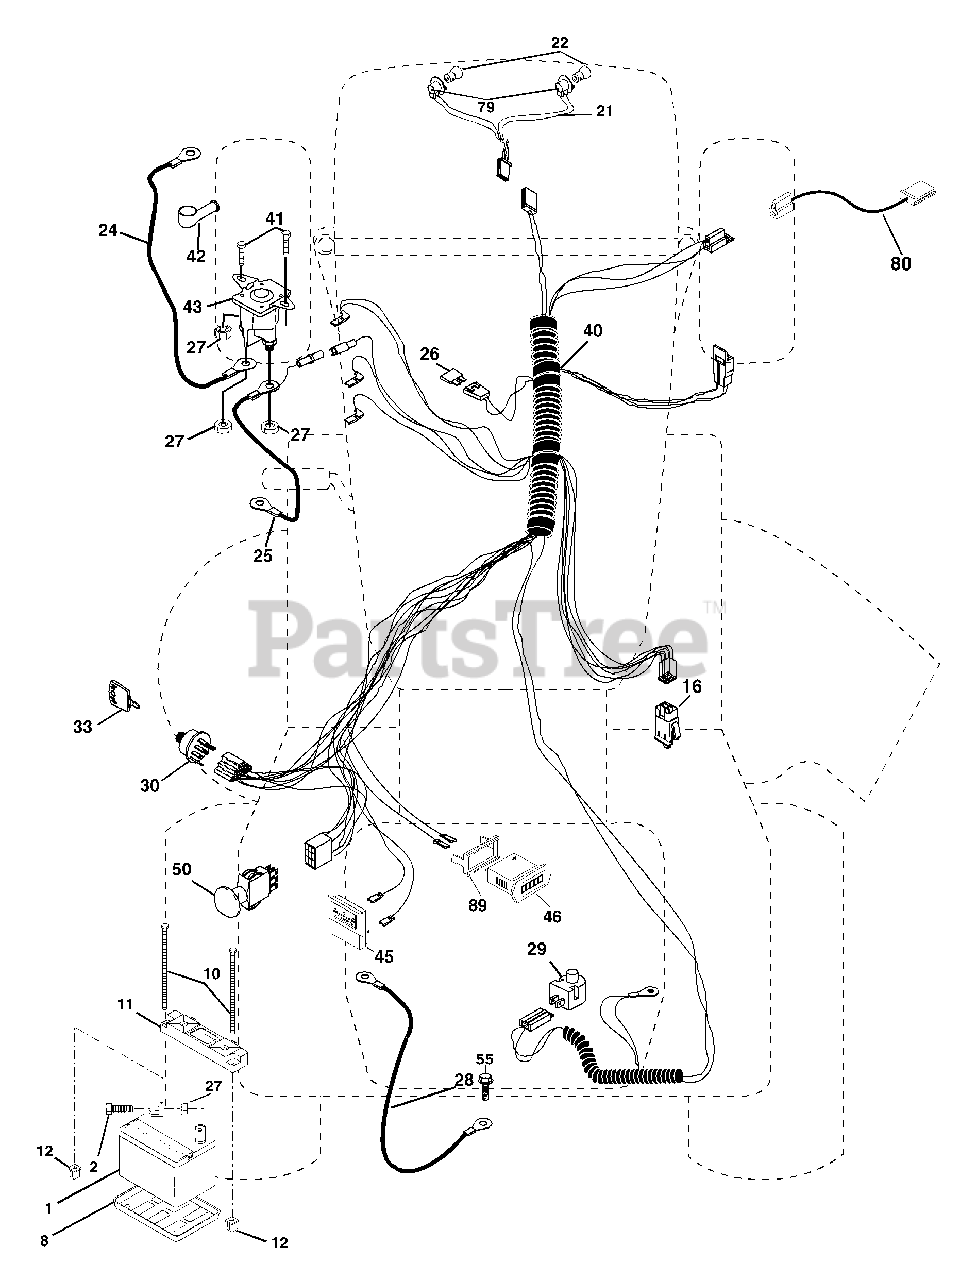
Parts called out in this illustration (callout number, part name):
1	Battery
2	Bolt, Hex 1/4-20 x 3/4
8	Tray, Battery
10	Bolt, Btr Front 1/4-20 x 7-1/2
11	Holddown Battery Front Mount
12	Nut, Push Nylon Battery Front 1/4
16	Switch Interlock
21	Harness, Light
22	Light Bulb
24	Cable, Starter
25	Cable, Battery
26	Fuse
27	Nut Keps Hex 1/4-20 Unc
28	Cable, Ground
29	Switch, Seat
30	Switch, Ignition
33	Key, Molded
40	Harness, Ignition
41	Screw Thd Cut 1/4-20 x 1/2
42	Cover, Terminal
43	Solenoid
45	Ammeter
46	Hourmeter
50	Switch, PTO
55	Screw Thdrol 5/16-18 x 1/2
79	Socket Asm bulb Twistlock
80	Harness Clutch EVX
89	Bracket Snap-In
